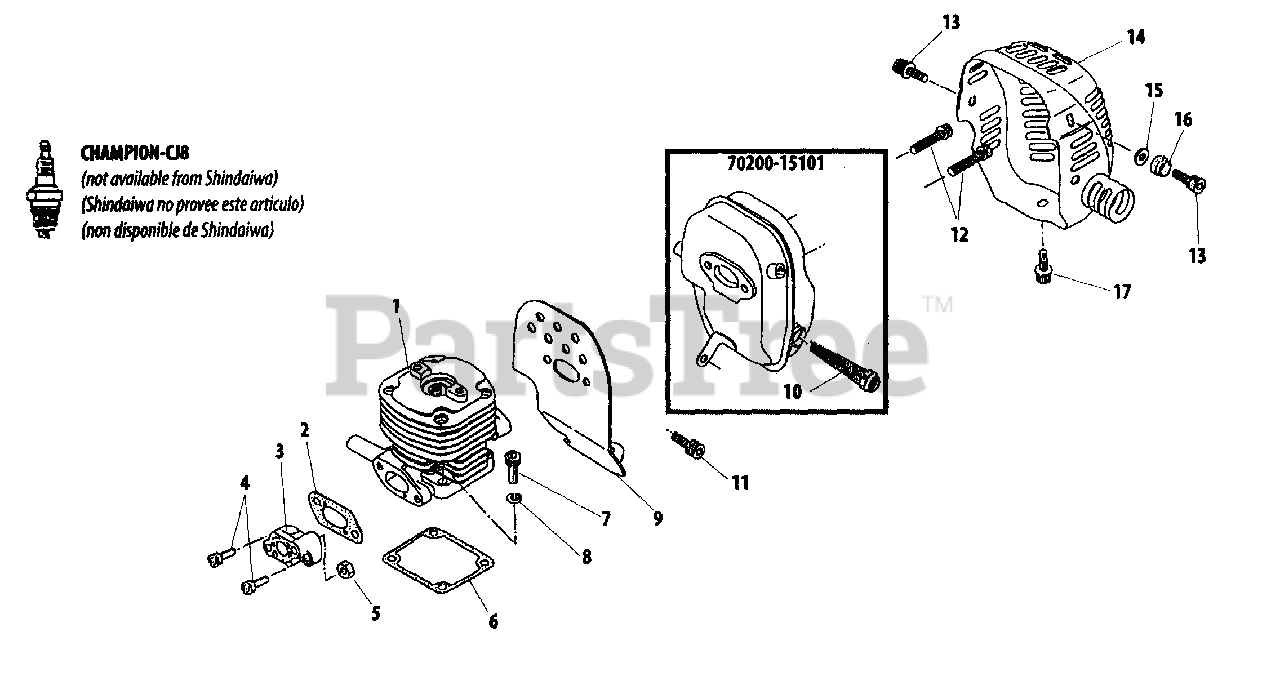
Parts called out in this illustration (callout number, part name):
1	CYLINDER
2	GASKET, INTAKE
3	INSULATOR
4	SCREW - 5X25
5	NUT
6	GASKET, CYLINDER
7	SCREW - 5X25
8	LOCKWASHER - 5
9	GASKET, EXHAUST
10	SCREEN, SPARK ARRESTOR
11	SCREW - 5X12
12	SCREW - 6X25
13	SCREW - 5X10
14	COVER, MUFFLER
15	WASHER
16	COVER
17	SCREW - 5X10
70200-15101	MUFFLER ASSY
